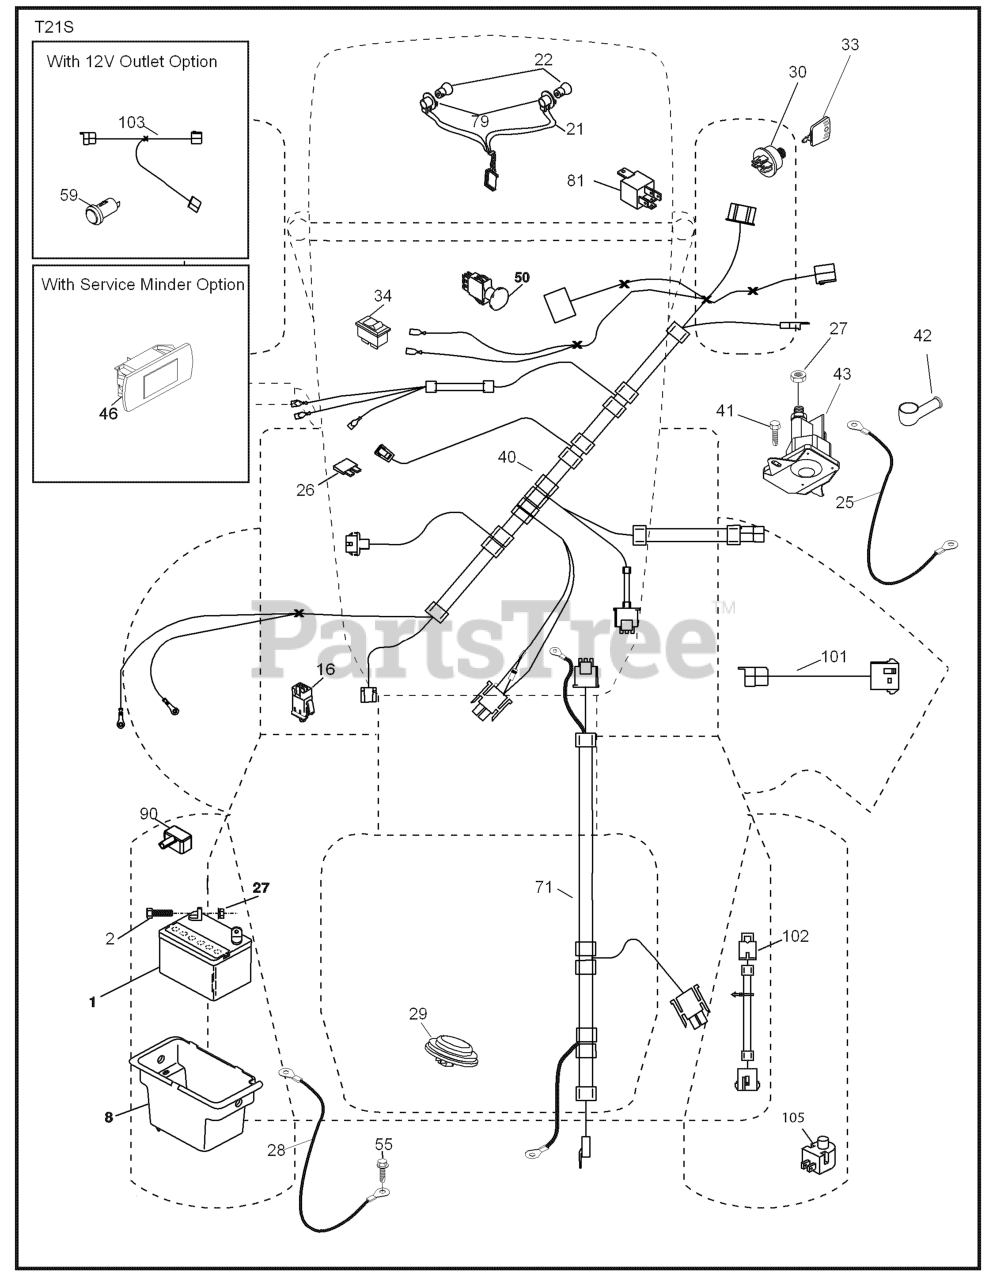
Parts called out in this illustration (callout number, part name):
1	Battery
2	BOLT.HEX.1/4.X.3/4.DICHROMATE
8	BOX.BATTERY.MNT.REAR.L
16	SWITCH INTERLOOK PUSH-IN
21	HARNESS ASSY LIGHT
25	CABLE.STARTER.6G.BL/RED.17.5
26	FUSE 20AMP
27	NUT
28	CABLE.BLACK.18"REAR.BA
29	SWITCH.SEAT.DELTA.OPC.
30	SWITCH.IGN.DELTA.W.LGH.ROS
33	KEY.CHAIN.BLISTER.PACK.GEN.INT
40	HARNESS.IGN.DASH.HUQ/P
41	SCREW
42	TERMINAL COVER
43	SOLENOID.W/BRASS.PLUNGER
46	RP.GUAGE.SRVCMNDR.HRMTR.
50	RP.PTO.SWITCH.8 TERMINAL.BLACK
55	SCREW 5/16"
59	OUTLET.12-VOLT
71	HARNESS.IGN.CHASS.TEX.REAR.BAT
79	BULB HOLDER ASM.
90	COVER, TERMINAL BATTERY
101	PIGTAIL.MATNLK.NEW.HAR
102	HARNESS PIGTAIL PCH TEX ROS
103	HARNESS PIGTAIL 12V OUTLET
105	REVERSE SWITCH
